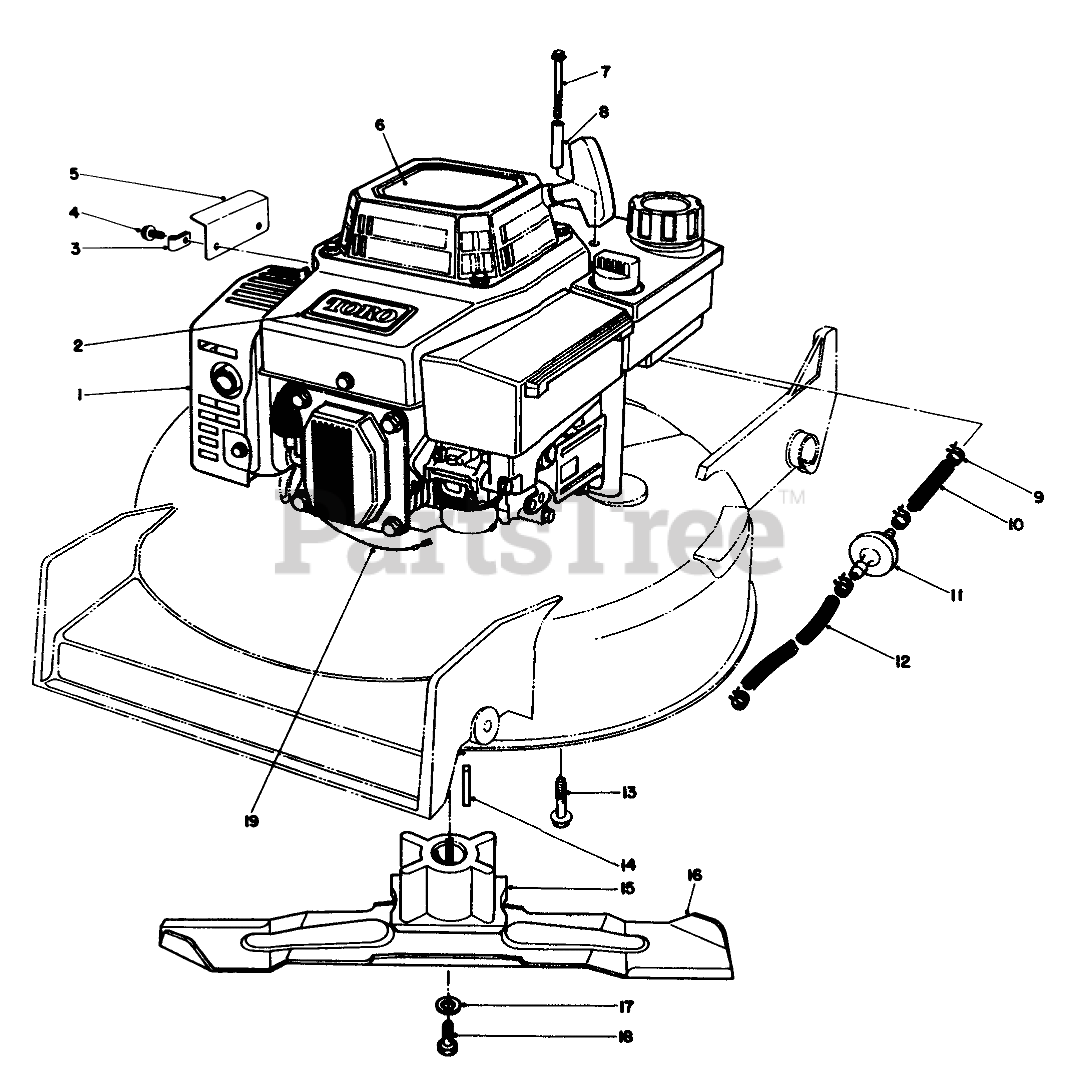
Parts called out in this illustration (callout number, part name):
2	TORO LOGO PLT
3	CLAMP-CABLE
4	THO FORM SCREW M6 X 1
5	FLYWHEEL SHIELD
6	DECAL-HV INT'L
7	THRD FORMING SCREW
8	TUBULAR SPACER
9	CLAMP-FUEL LINE
10	LINE-GAS
11	FILTER-FUEL
12	HOSE-FUEL
13	SCREW-HWHTF
14	KEY-SQUARE
15	Retainer Blade
16	BLADE-21in
17	WASHER-LOCK
18	SCREW-BLADE
19	Wire Assembly
